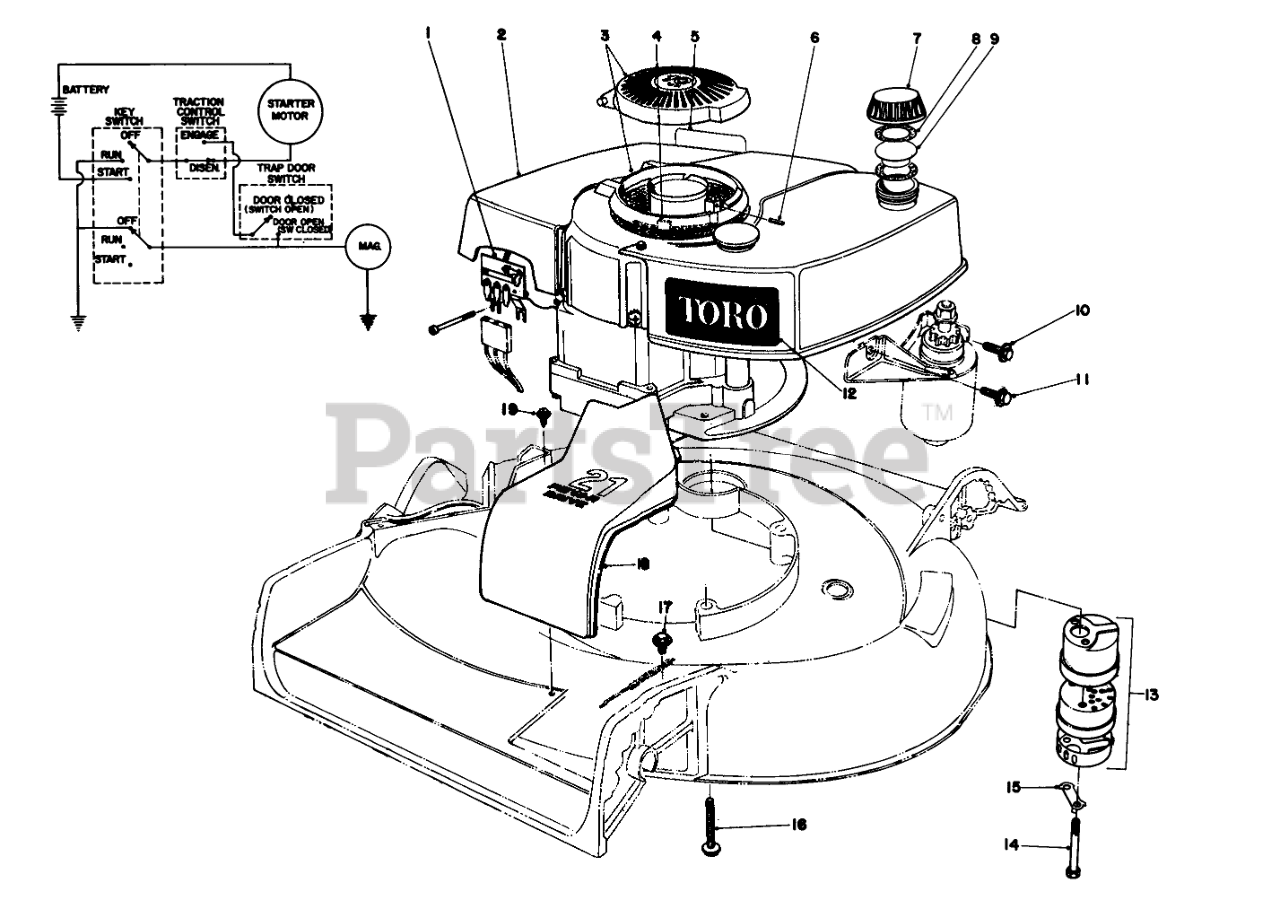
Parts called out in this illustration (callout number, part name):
1	SWITCH & TERM BLK CVR
2	Engine
3	Cover Assembly
4	WIRE CLIP
5	Decal-Maintenan
6	SPRING PIN
7	Gas Cap (Incl. Ref. #8 & 9)
8	GASKET
9	GAS CAP BAFFLE
10	SCREW
11	Screw
12	Decal Tow
13	Muffler Assembly (IncI. Ref. #14 & 15)
14	SCREW-HH
15	CLIP - LOCKING
16	3/8-16 X 2-3/4 CAPSCR
17	SCREW-HWHTF
18	BELT DRIVE COVER
19	SCREW
